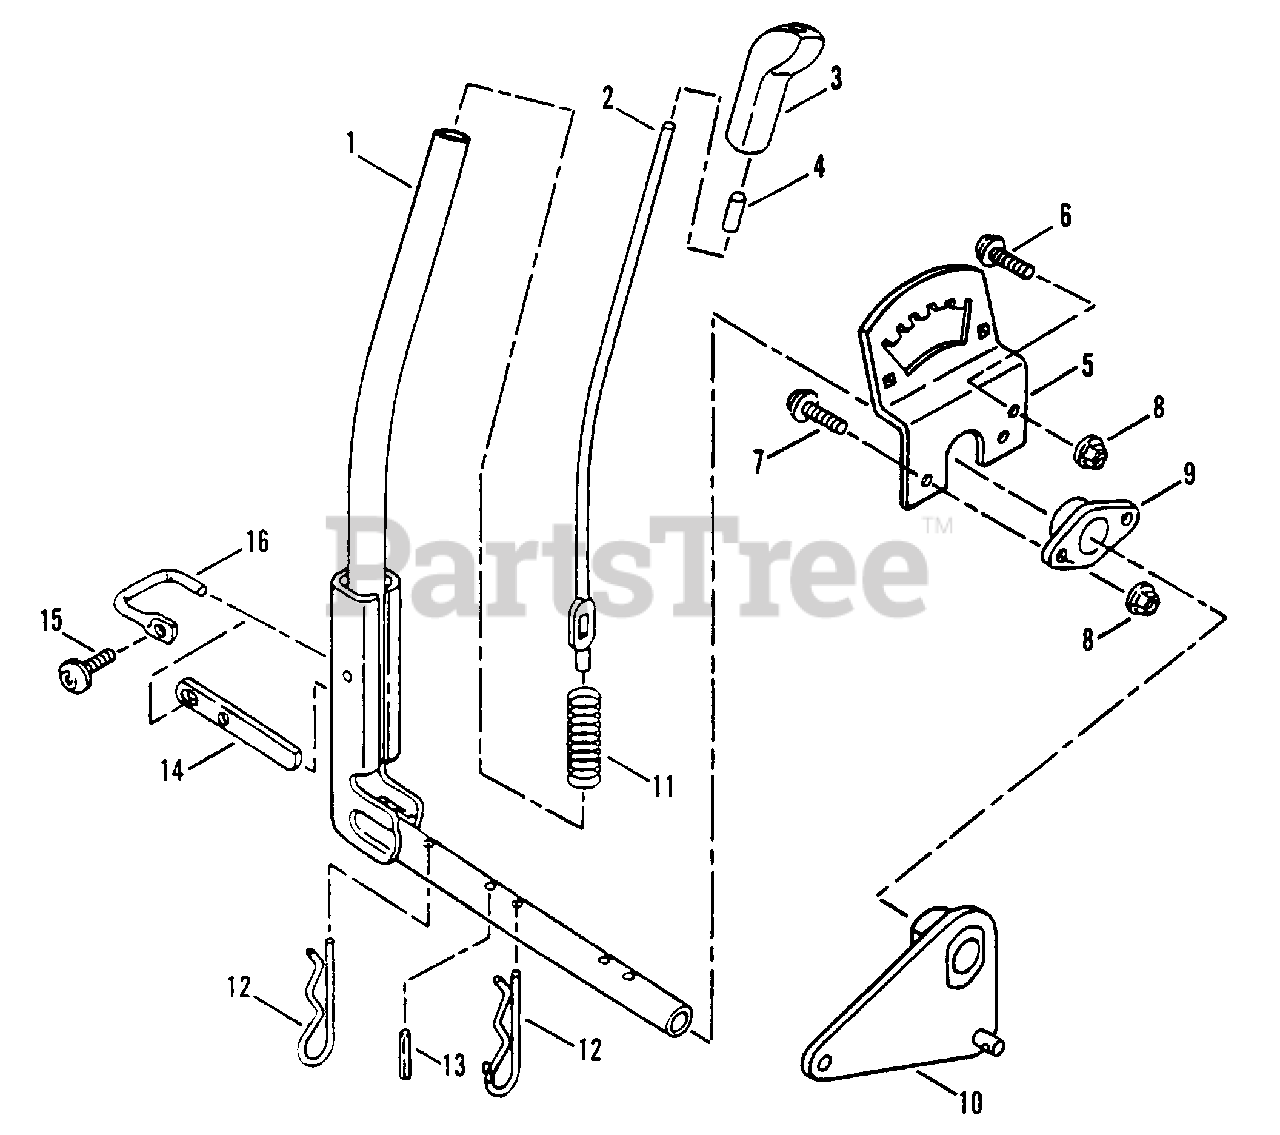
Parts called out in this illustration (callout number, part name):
1	LEVER, Implement Lift
2	ROD, Lift Lever
3	KNOB, Lift Lever
4	CAP, Lift Lever Rod
5	QUADRANT, Lift Lever
6	SCREW, 5/16-18 x 5/8" Truss Head (Torx)
7	SCREW, 5/16-18 x 7/8" Truss Head (Torx)
8	NUT, 5/16-18 Hex Flange Lock
9	PIVOT, Lift Lever
10	BELLCRANK, Lift Lever
12	HAIR-PIN, 5/32 x 2 5/8"
13	PIN, Dowel, 1/4 x 1 1/8"
14	DETENT, Latch
15	SCREW, 1/4-20 x 5/8" Truss Head (Torx)
16	LATCH, Pivot
